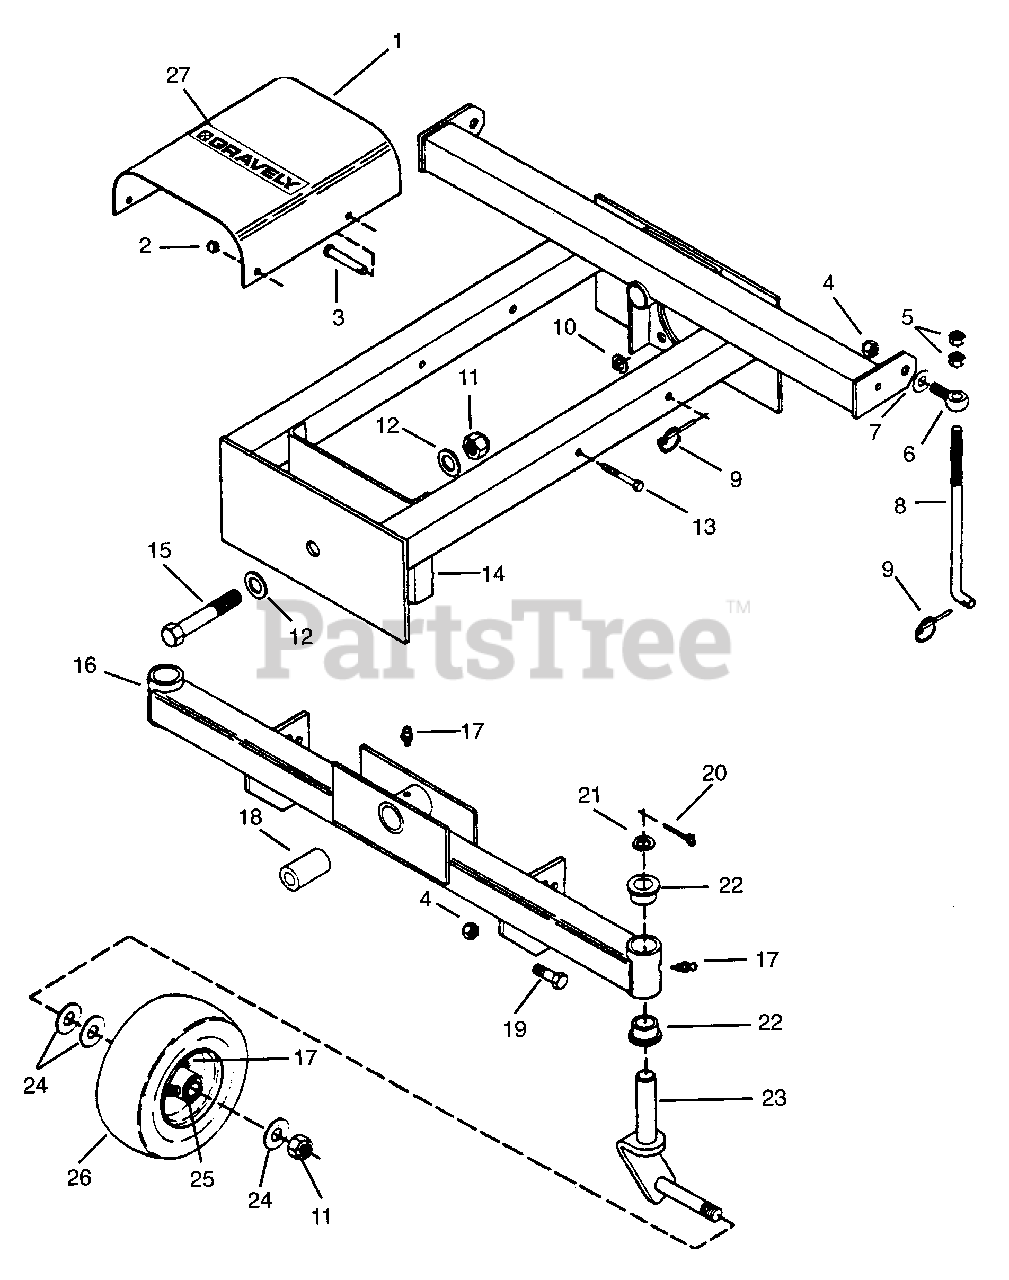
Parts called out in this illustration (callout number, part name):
1	Guard, PTO Shaft
2	Nut-Locking-Nylon .312-18 Grade 2
3	Pin-Clevis .38 x 2.62
4	Nut-Locking-Nylon .50-13 Grade 5
5	Nut-Jam .50-13 Grade 2
6	Bolt-Eye .56 x 2.12
7	Washer-Flat-Steel .500 x 1.250 x .083
8	Rod, Height Adjuster
9	Pin-Klik 1.000 x .188 x 1.25
10	Washer-Lock .50 Reg.
11	Nut-Locking-Nylon .75-10 Grade 2
12	Washer-Flat-Steel .700 x 1.470 x .134
13	Bolt-Hex .31-18 x 2.50 Grade 5
14	Weldment, Mower Frame
15	Bolt-Hex .75-10 x 4.50
16	Weldment, Axle
17	Fitting-Lube .25-28 x .256
18	Tube, Pivot
19	Bolt-Hex .50-13 x 1.375
20	Pin-Cotter .188 x 1.625
21	Washer-Hardened-Thrust 1.00 x 1.55 x .03
22	Bushing-Flange 1.020 x 1.385 x .75 x 1.75
23	Weldment, Caster Fork
24	Washer-Flat .812 x 1.469 x .134
25	Bearing, Gauge Wheel
26	Wheel 9 x 3.50
27	Decal, Gravely Logo
